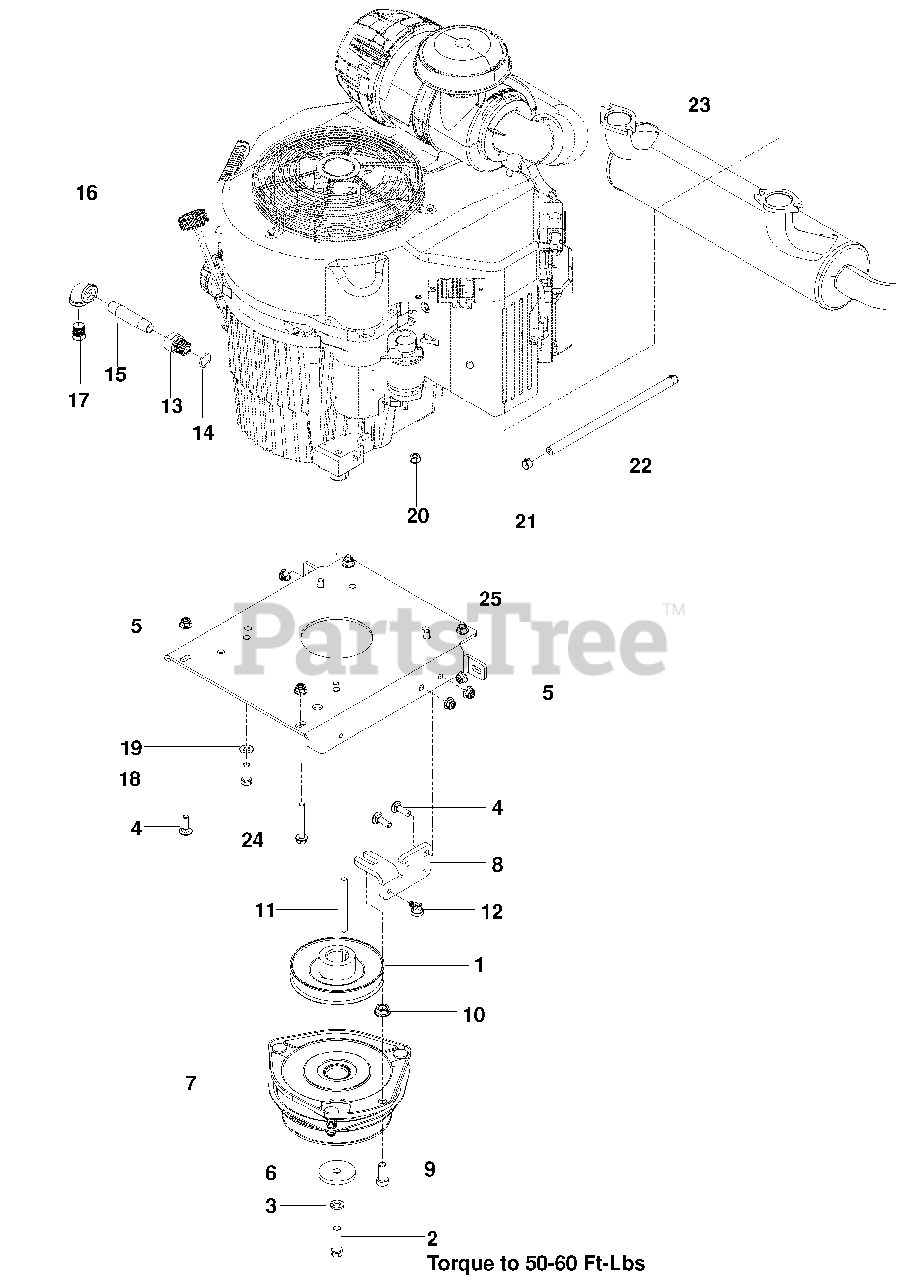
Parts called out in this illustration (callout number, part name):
1	Pulley, Engine
2	Bolt 7/16-20 X 1 1/2 Hex Nyl
3	Washer 7/16 Slw
4	Bolt 5/16-18 X 1 Rd Hd
5	Nut 5/16-18 Hex Flg Nyloc
6	Washer, Blade
7	Clutch, Gt 3.5
8	Stop, Clutch
9	Bolt 7/16-14 X 1 Hex Nyloc
10	Nut 7/16-14 Hex Whiz Lk
11	Key 1/4 Sq X 3 1/2
12	Tie Wrap W/ Clip
13	Adaptor, Oil Drain
15	Pipe 3/8 Npt X 3"
17	Plug, Drain, 3/8 Nptf
18	Bolt 3/8-16 X 1 Hex Nyloc
19	Washer 3/8 Spring
20	Nut M8X1.25 Nyloc
21	Clamp, Hose
22	Fuel Line 10"
23	Muffler 966060901
24	Screw 5/16-18 X 2 1/4 Hex Flg
25	Plate, Engine
